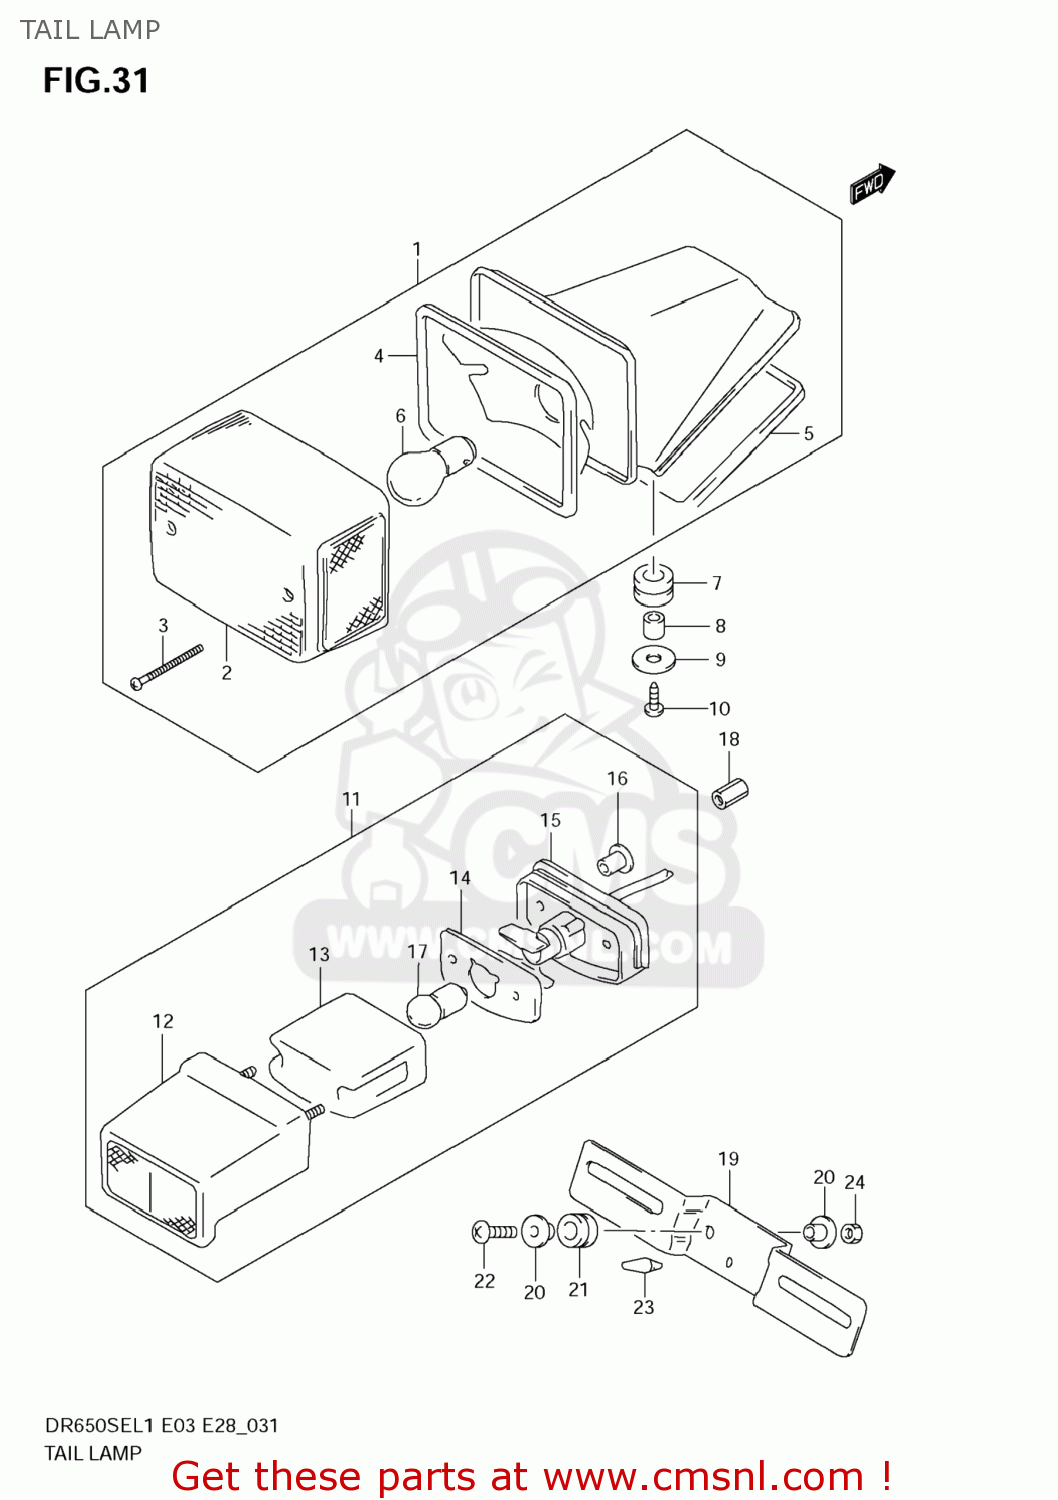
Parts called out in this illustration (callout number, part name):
1	LAMP ASSY,RR COMBINATION
2	LENS,TAIL LAMP
3	SCREW(4X45)
4	GASKET,LENS (NAS)
5	GASKET (NAS)
6	BULB(12V21/5W)
7	CUSHION
8	SPACER(6.1X8X9.5)
9	WASHER(6.5X20X1.6)
10	SCREW
11	LAMP ASSY,LICENSE
12	COVER,LICENSE
13	LENS
14	GASKET,LICENSE LAMP (NAS)
15	CUSHION
16	SPACER
17	BULB(12V5W,BF150-40160A)
18	NUT
19	BRACKET,LICENSE PLATE
20	WASHER
21	CUSHION
22	SCREW
23	CUSHION
24	NUT
